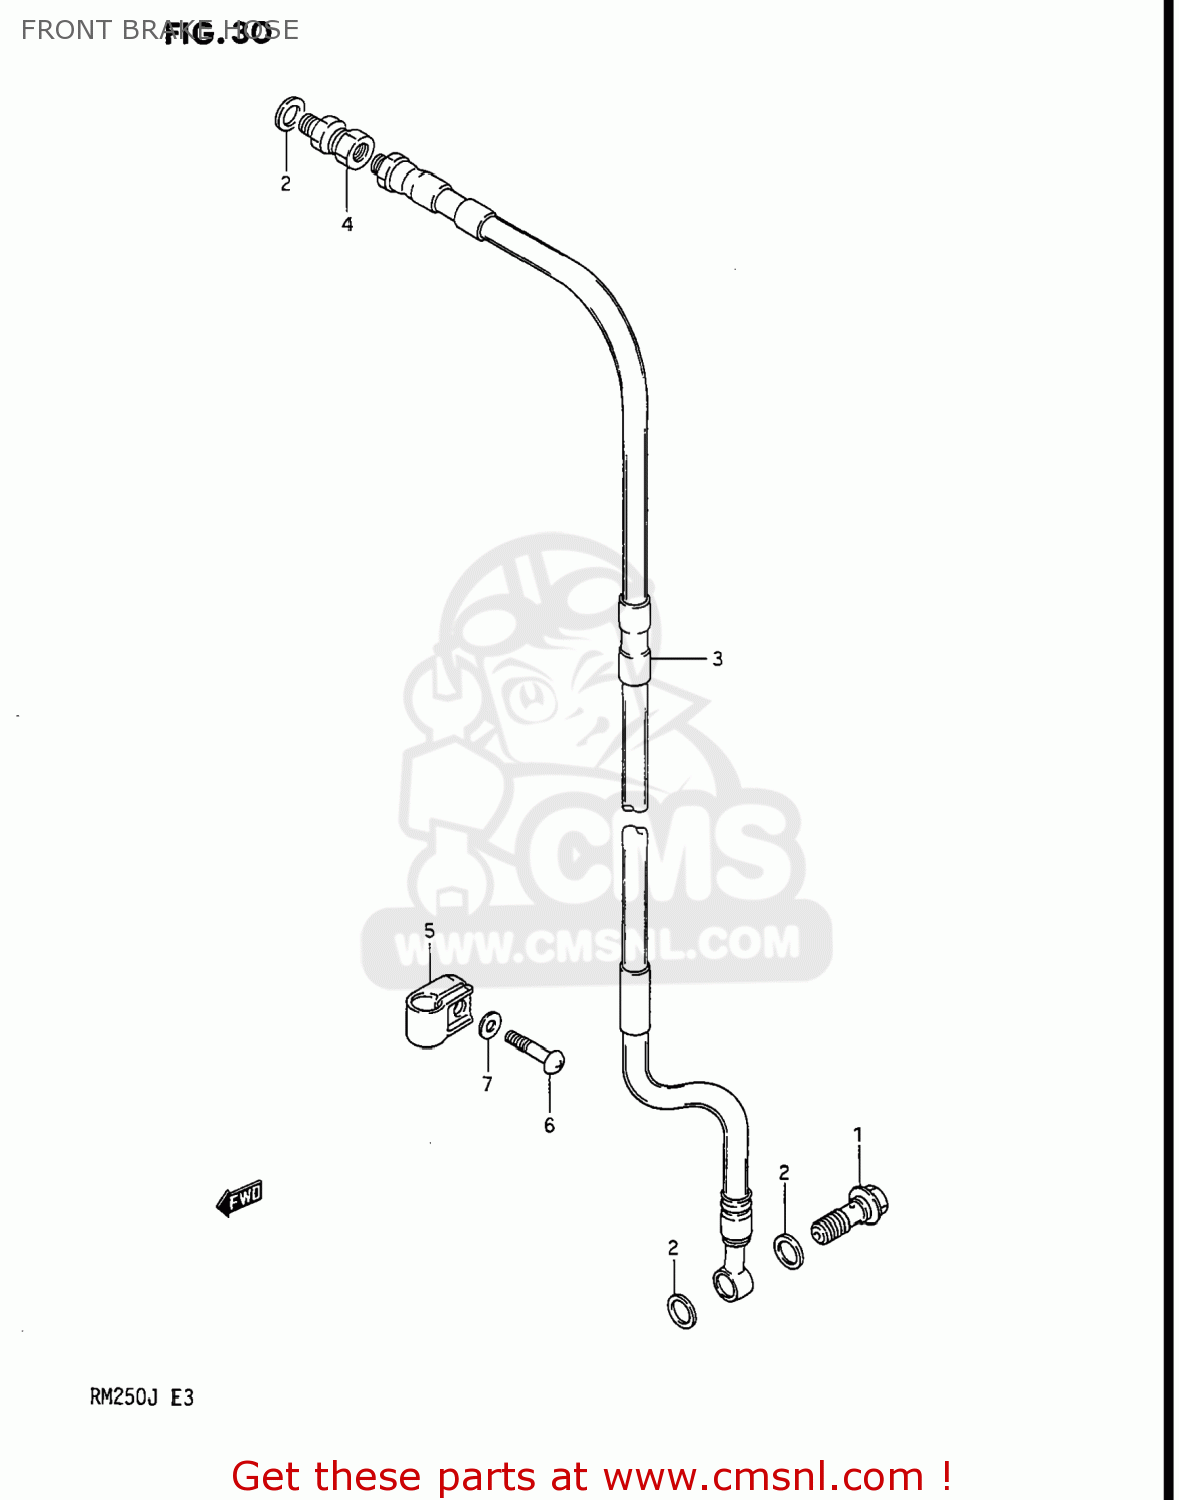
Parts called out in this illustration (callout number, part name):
1	BOLT UNION
2	WASHER(10X15X1.5)
3	HOSE,FRONT BRAKE
4	ADAPTER,BRAKE HOSE
5	CLAMP,FRONT BRAKE HOSE
6	SCREW
7	WASHER
